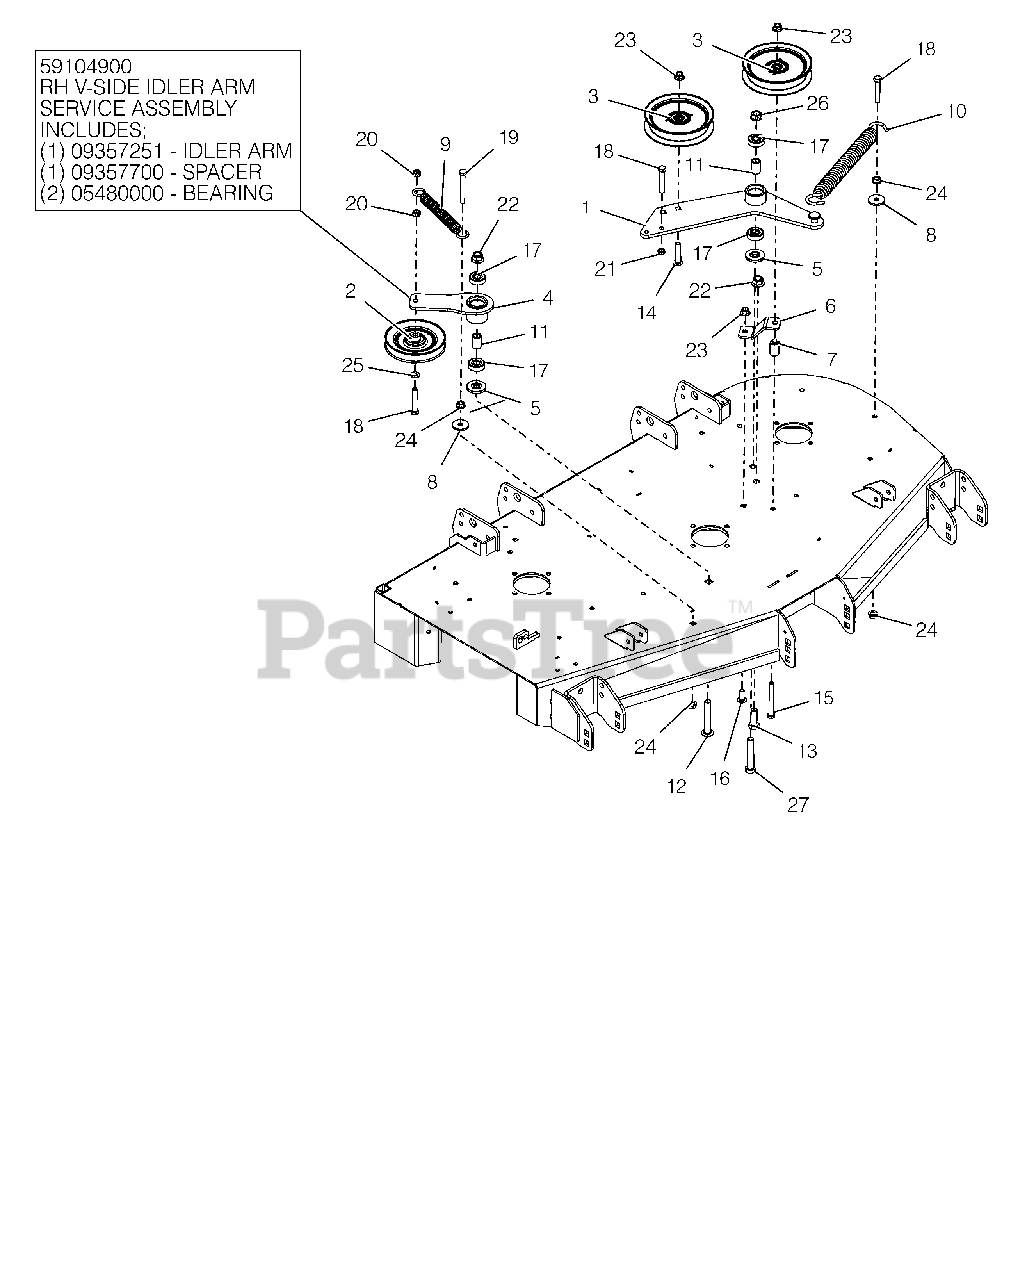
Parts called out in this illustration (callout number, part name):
1	DECK PTO IDLER ARM WLDMT - BLK
2	IDLER, V-5.00"
3	IDLER, FLAT 5.00"
4	DECK RH IDLER ARM WMT - BLK
4	RH V-SIDE IDLER ARM ASSEMBLY
4	SPACER .510 X .75 X 1.1485
4	BRG-BALL .50X1.38X.438 SEALED
5	SPACER, IDLER ARM
6	PTO FIXED IDLER MTG BRKT -RED
7	BUSHING, SLV .380X.750X1.190
8	WSHR-FL-STL .406X1.375X.135 YZ
9	SPRING, EXTENSION
10	SPRING, EXTENSION
11	SPACER .510 X .75 X 1.1485
12	BLT,RDHDSQSHNK.50-13X3.25 G5YZ
13	@BLT-HEX .50-13X1.50 GR5 YWZC
14	BLT-RDHDSQNK .38-16X2.00 SHTYW
15	@BLT-HEX .38-16X3.25 GR5 YWZC
16	@BLT-RDHDSHSQNK.38-16X1.0 G5YZ
17	BRG-BALL .500X1.38X.437
18	@BLT-HEX .38-16X2.25 GR5 YWZC
19	@BLT-HEX .38-16X3.00 GR5 YWZC
20	@NUT-LK-CTR .38-16 YWZC
21	NUT-HEX-JAM .375-16 YWZC
22	@NUT-LK-NYL-FLG .50-13 YWZC
23	@NUT-LK-NYL-FLG .38-16 YWZC
24	@NUT-SPNLK-FLG .375-16 YWZC
25	@WSHR-FL-STL.406X.812X.065 YWZ
26	NUT-LK-CTR-FLG .50-13 YWZC
27	@BLT-HEX .50-13X3.00 GR5 YWZC
